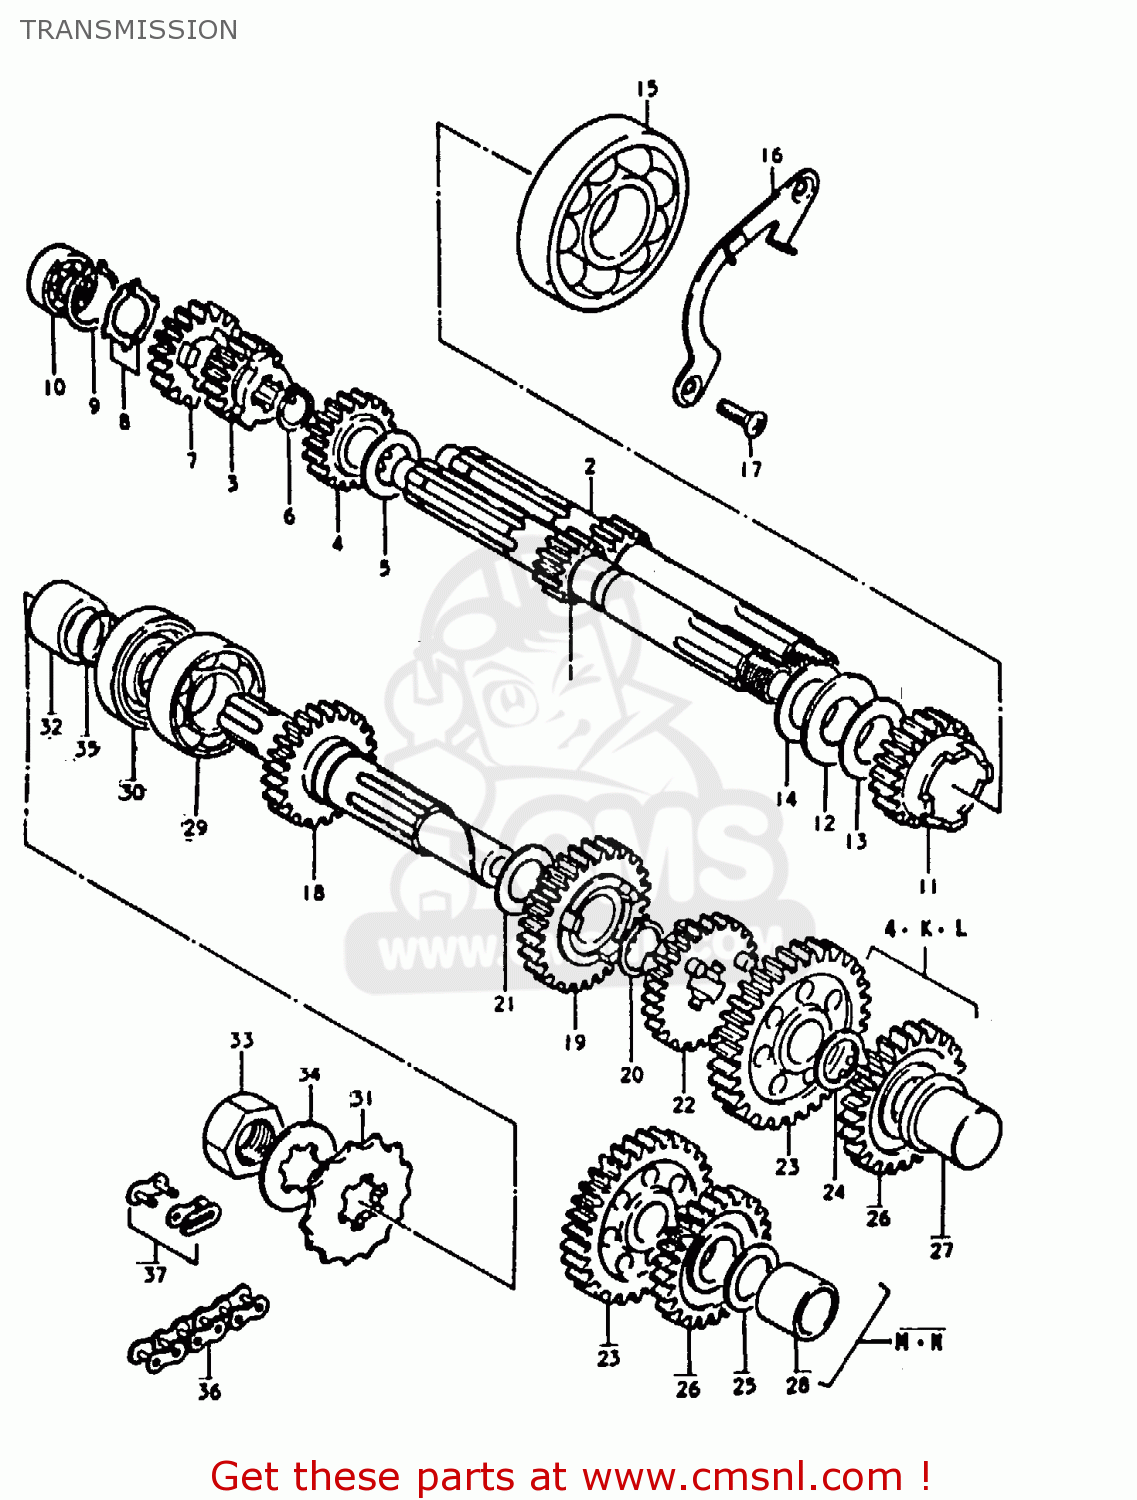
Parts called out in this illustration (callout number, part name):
1	COUNTERSHAFT
3	GEAR,SECOND DRIVE
4	GEAR,THIRD DRIVE
5	WASHER
6	CIRCLIP
7	GEAR,FOURTH DRIVE
8	RING
9	RING,SNAP
10	BEARING(12X28X8)
11	GEAR,KICK STARTER DRIVE
12	BEARING(20.1X35X2.8)
13	WASHER (20.1X29.5X0.8)
14	WASHER(20X34X0.8)
15	BEARING
16	PLATE,COUNTERSHAFT BEARING
17	SCREW
18	SHAFT,DRIVE
19	GEAR,SECOND DRIVEN
20	CIRCLIP
21	WASHER,THRUST
22	GEAR,THIRD DRIVEN
23	GEAR,FIRST DRIVEN
24	WASHER,THRUST
26	GEAR,KICK STARTER IDLE
27	BUSHING
29	Bearing
30	SEAL,OIL(25X40X9)
31	SPROCKET,ENGINE
32	SPACER(20X25X15.5)
33	NUT
34	WASHER,LOCK
35	O RING(D:1,ID:19.5)
36	CHAIN ASSEMBLY,DRIVE
37	JOINT ASSEMBLY,CHAIN
